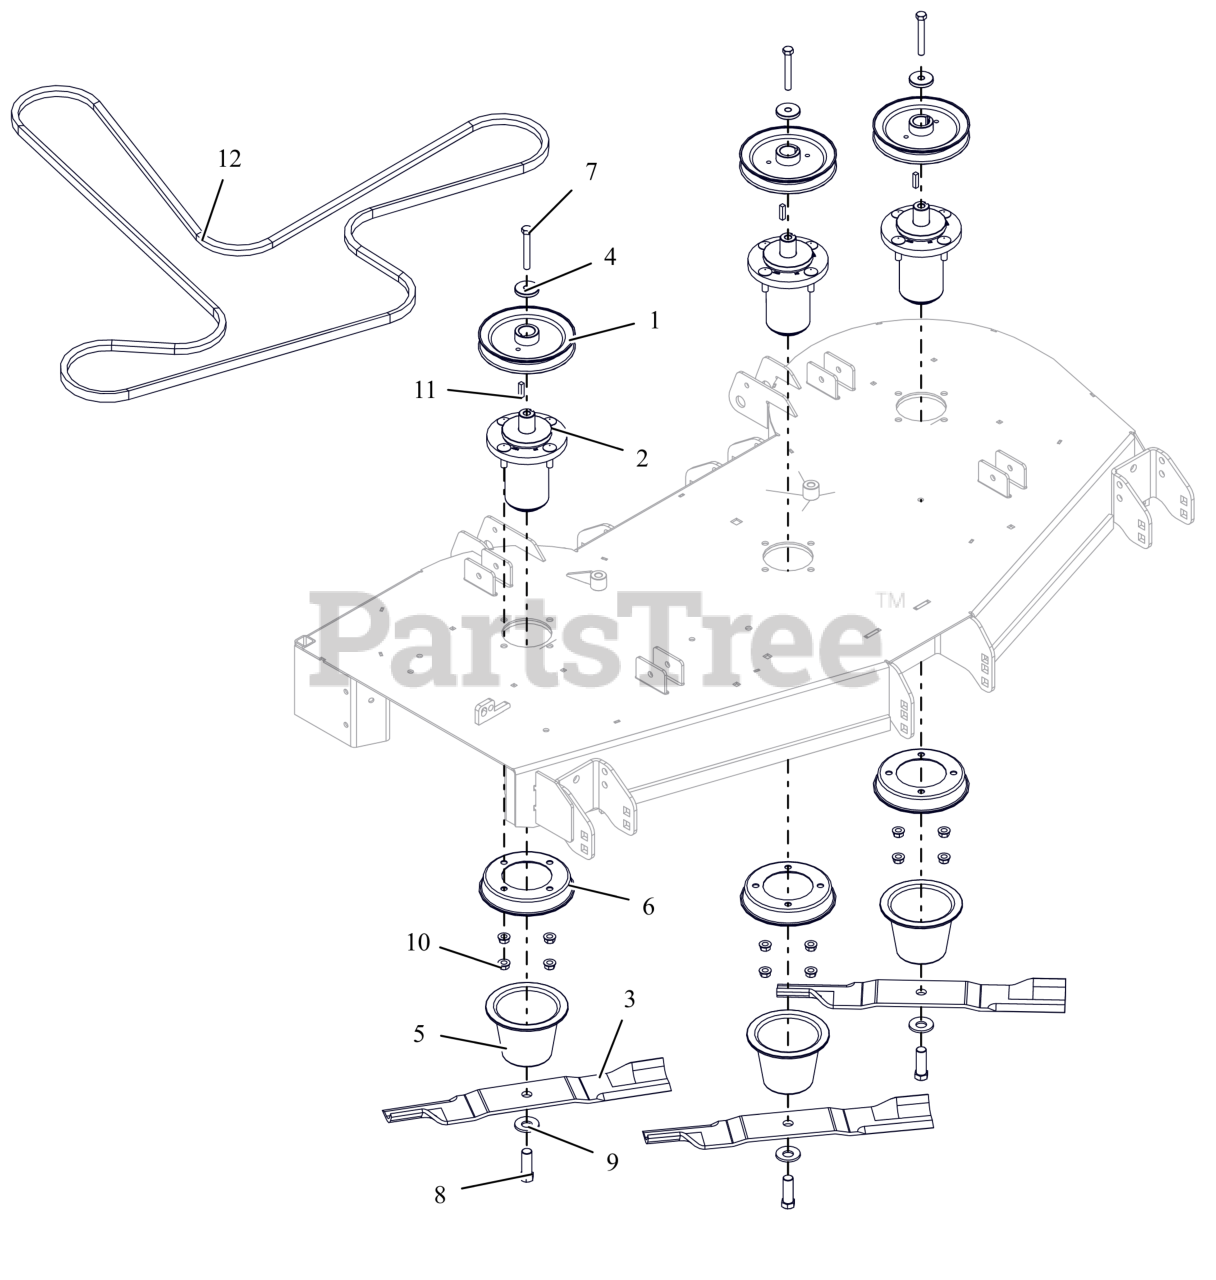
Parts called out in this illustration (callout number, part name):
1	PULLEY, V-1" ID X 6.00 OD
2	ASM, MAINT FREE ALUM SPINDLE
3	BLADE, 18.00" MOWER (HI-LIFT)
4	RETAINER, SHEAVE
5	GUARD, SPINDLE LOWER
6	GUARD, SPINDLE TOP
7	BLT, HEX .38-16X2.75 G8 ZCC
8	BLT, HEX .62-18X1.75 G8 ZCC
9	WSHR-BLVL .669X1.535X.138
10	NUT-LK-CTR-FLG .375-16 GF ZCC
11	KEY, SQ .25X.25X1.00 RC 40-50
12	V-BELT, B RAW EDGE EPDM
